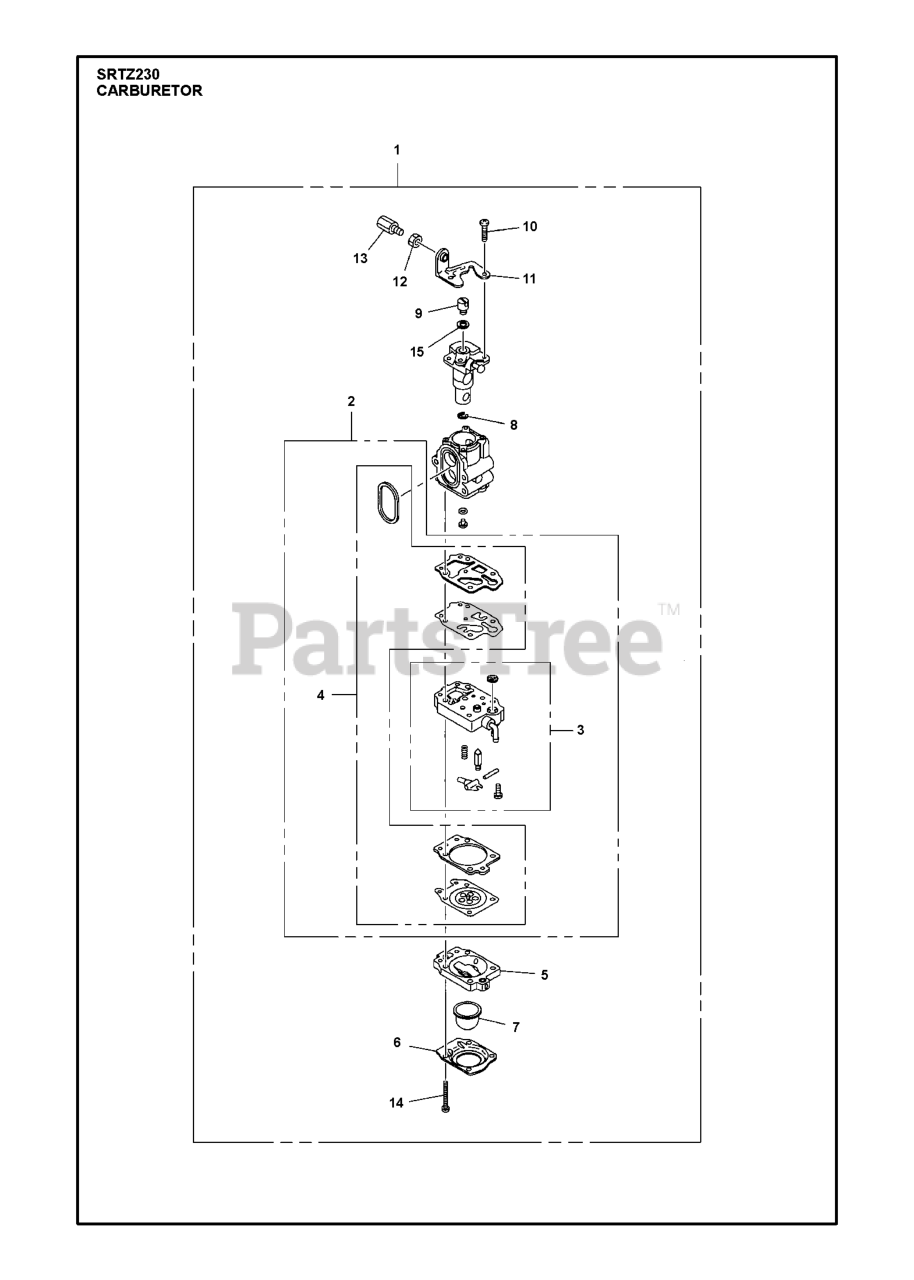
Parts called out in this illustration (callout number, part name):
2	REBUILD KIT
4	GASKET KIT
6	1OVER
8	RING
9	SWIVEL
10	SCREW
11	BRACKET
12	NUT
13	ADJUSTER
15	WASHER
